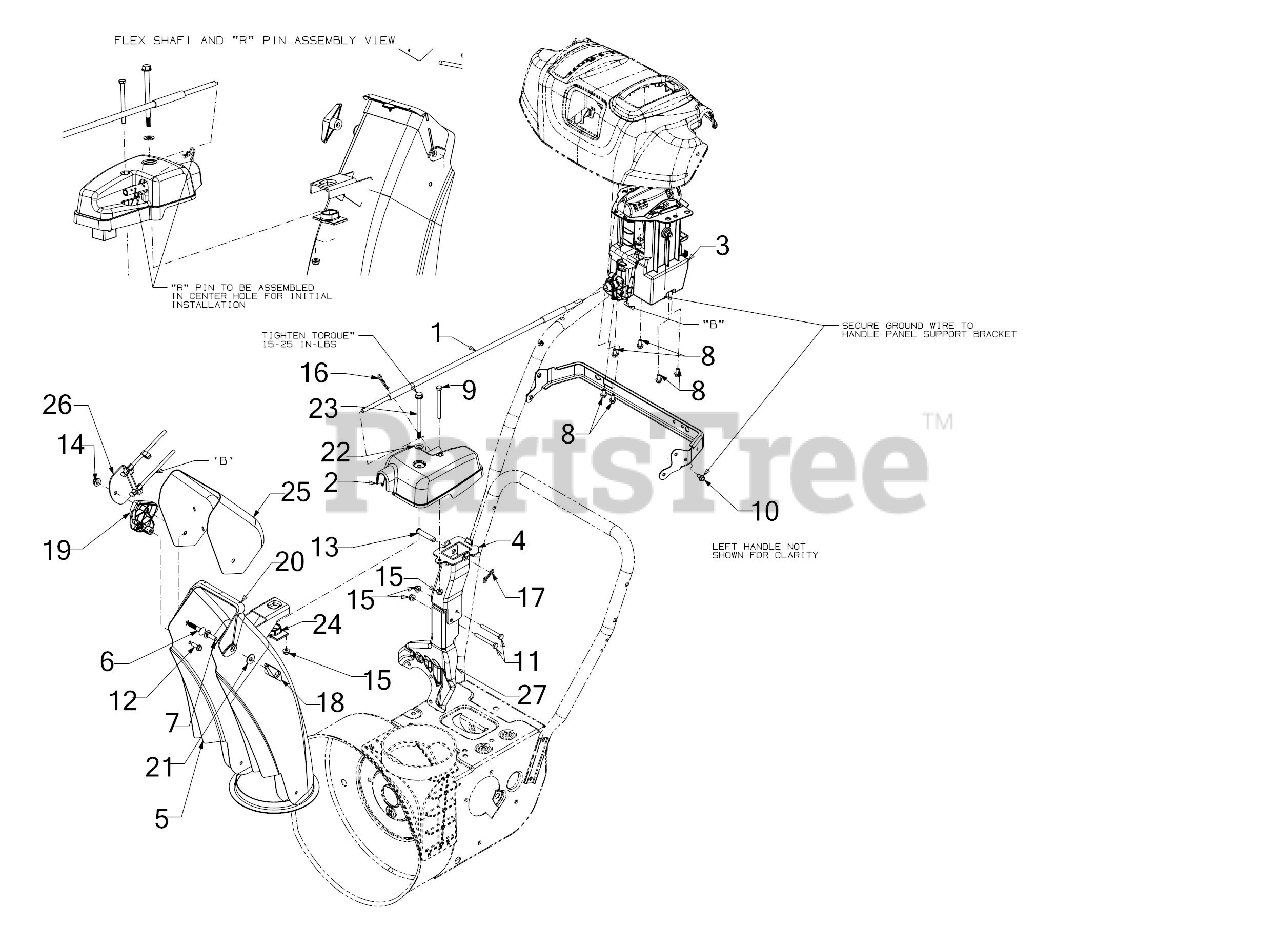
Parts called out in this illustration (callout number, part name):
1	ELECTRIC 4-WAY CHUTE CONTROL SHAFT
2	WORM GEARBOX ASSEMBLY
3	4-WAY CHUTE CONTROL ASSEMBLY
4	CHUTE MAST BRACKET
5	LOWER STEEL CHUTE 6" DIA
6	CARRIAGE BOLT 5/16-18 x 1.50
7	CARRIAGE BOLT 5/16-18 x 1.00
8	HEX SCREW 1/4-15 x .50
9	SCREW 1/4-20 x 3.0 GR5
10	SCREW 1/4-20 X.500
11	SCREW 1/4-20 x 2.25 GR5
12	SCREW 1/4-15 x .750
13	CLEVIS PIN 3/8 x 1.87
14	FLANGE LOCK NUT 5/16-18
15	FLANGE LOCK NUT
16	INTERNAL COTTER PIN
17	BOW TIE COTTER PIN 1/4-5/16
18	WING NUT KNOB
19	CHUTE TILT GUIDE
20	UPPER CHUTE ADAPTER
21	FLAT WASHER
22	FLAT WASHER
23	SHOULDER SCREW
24	HELICAL GEAR CHUTE ADAPTER
25	UPPER CHUTE STEEL
26	CABLE BRACKET GUIDE
27	CHUTE SUPPORT BRACKET
